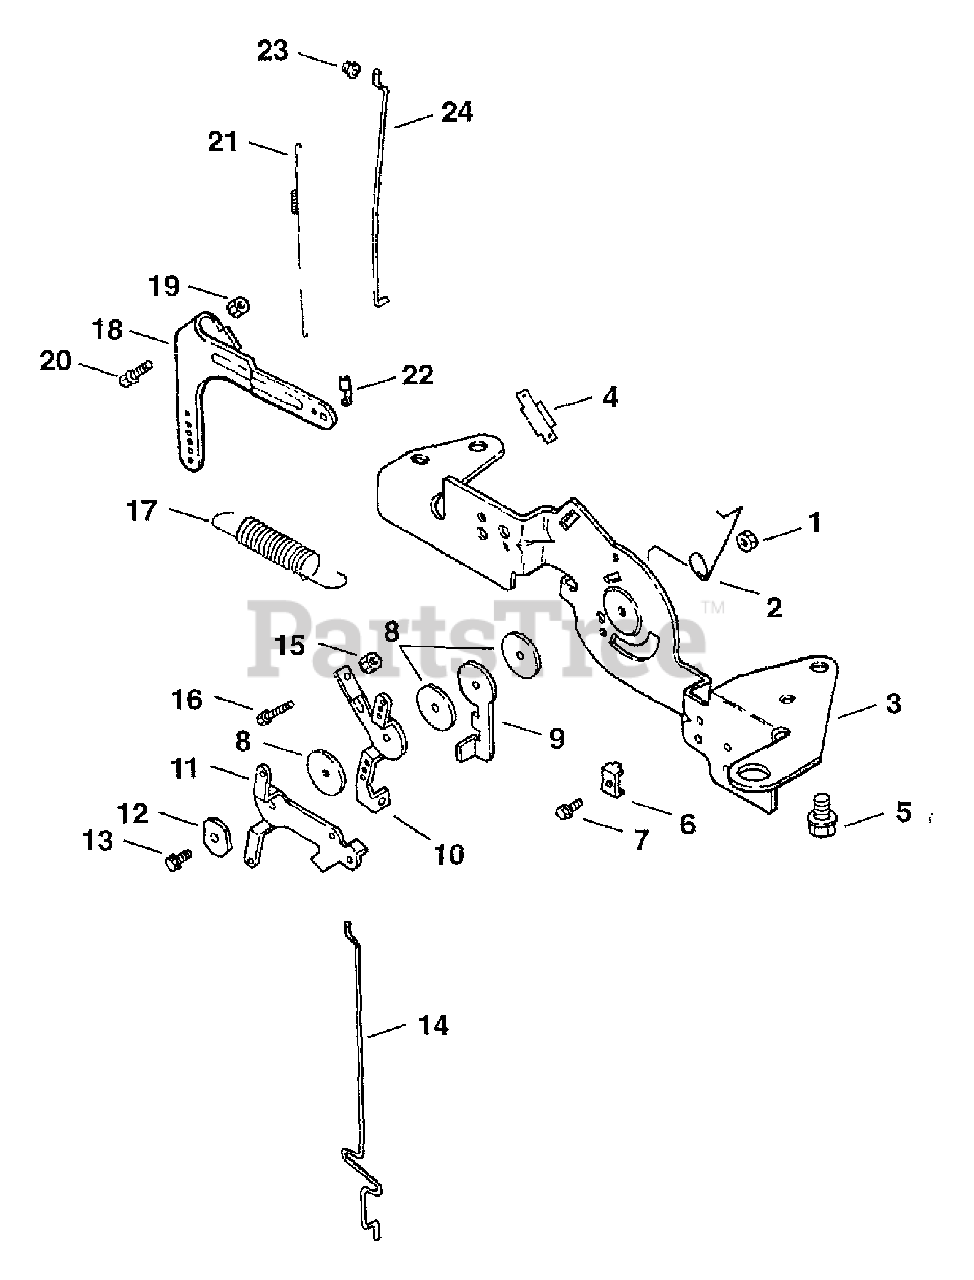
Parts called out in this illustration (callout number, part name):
1	Nut, hex. flange M5x0.8
2	SPRING, CHOKE RETURN
3	BRACKET, CONTROL-USE 24 126 176-S
5	SCREW - USE M-645016
6	CLAMP, CABLE
7	SCREW - USE M-545016
8	WASHER, FLAT 5.5 MM
9	LEVER,THROTTLE ACTUATOR-USE(24 090 65-S
10	LEVER, THROTTLE CONTROL
11	LEVER, CHOKE
12	WASHER, SPRING 1/4"
13	Screw, hex. flange 5x0.8x20
15	Nut, hex. flange M4x0.7
16	Screw, hex. cap M4x0.7x25
17	SPRING, GOVERNOR (CLEAR)
18	LEVER, GOVERNOR - DISCONTINUED
19	NUT - USE M-641060
20	USE SM-642025-S
21	SPRING, LINKAGE
22	BUSHING, THROTTLE LINKAGE
23	BUSHING, LINKAGE RETAINING
24	LINKAGE, THROTTLE
